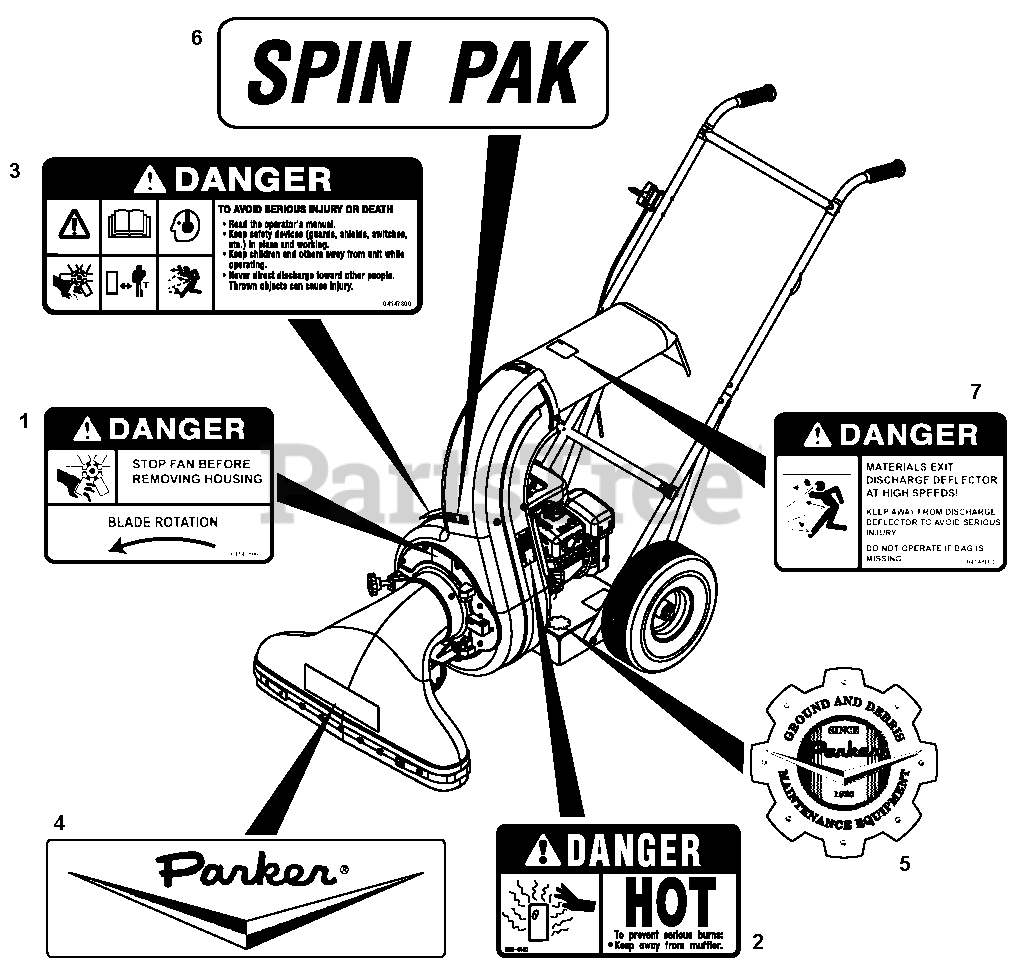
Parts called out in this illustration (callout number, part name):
1	Decal, Danger Blade Rotation
2	Decal, Danger Hot
3	Decal, Danger Read Manual
4	Decal, Parker Logo
5	Decal, Parker Heritage, Small
6	Decal, Spin Pak
7	Decal, Danger Discharge
